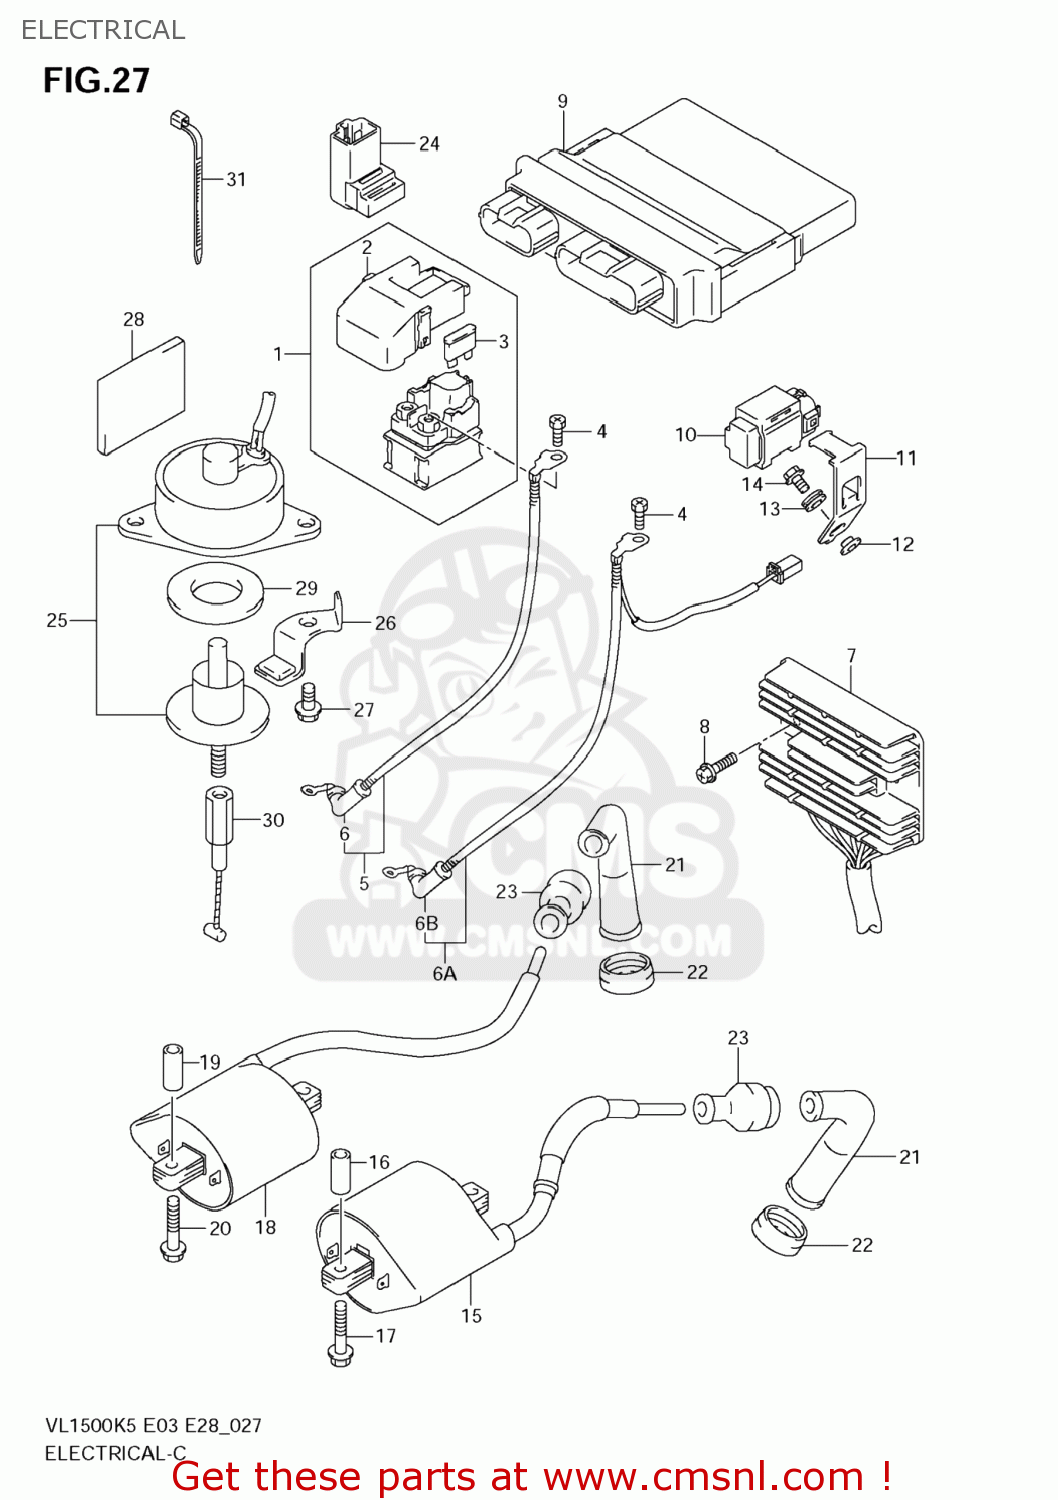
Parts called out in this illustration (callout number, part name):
1	RELAY ASSY,STARTING MOTOR
2	COVER
3	FUSE(30A)
4	SCREW(6X8)
5	WIRE,STARTER MOTOR LEAD
6	CAP,STARTER MOTOR LEAD
6A	WIRE,STARTER MOTOR LEAD
6B	CAP,STARTER MOTOR LEAD
7	RECTIFIER ASSY
8	SCREW
9	CONTROL UNIT,FI
10	SENSOR ASSY,FUEL CUT
11	BRACKET,FUEL CUT SENSOR
12	SPACER(6.2X8.4X6.9)
13	CUSHION
14	BOLT
15	COIL ASSY,IGNITION RR
16	SPACER(6.4X10X18)
17	BOLT
18	COIL ASSY,IGNITION FR
19	SPACER(6.4X10X18)
20	BOLT
21	CAP,SPARK PLUG
22	SEAL,SPARK PLUG
23	SEAL,HIGH TENSION CORD
24	RELAY ASSY
25	SOLENOID ASSY,DECOMP
26	STOPPER,DECOMP SOLENOID
27	BOLT
28	CUSHION,BATTERY(80X27X3)
29	CUSHION,DECOMP
30	CABLE ASSY,DECOMP FR
31	CLAMP(L:235)
